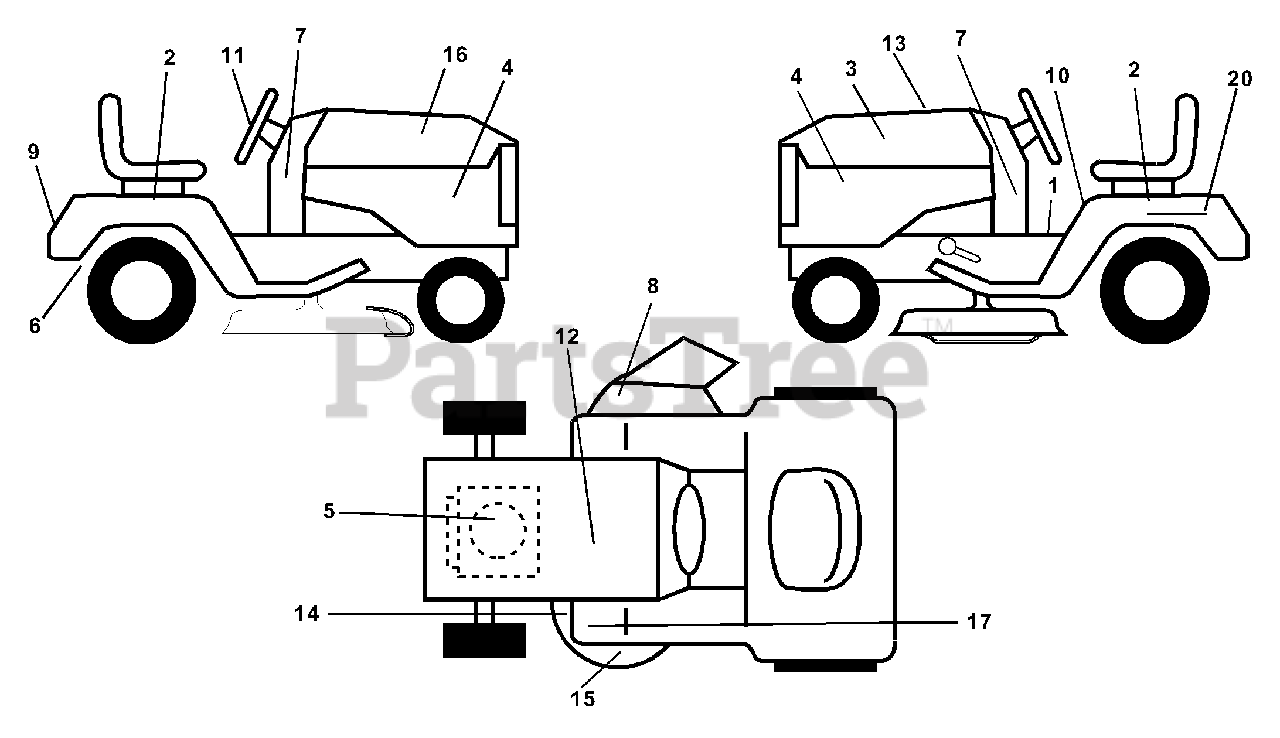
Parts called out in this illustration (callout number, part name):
1	Decal Oper
2	Decal Fender Auto
3	Decal Hood LH
4	Decal Side Panel Logo
5	Decal HP Engine
6	Decal By Pass Lt Hydro
7	Decal Dash Panel
8	Decal Mower Warn Keep Hand Away
9	Decal Fender Logo
10	Decal Fender Danger E/F
11	Decal Ins Strg Whl
12	Decal Battery
13	Decal Replacement Parts
14	Decal V-Belt Schematic
15	Decal Deck Mulch Vented
16	Decal Hood Rh
17	Decal Clutch/Brake
20	Decal Bat Dan/Psn
